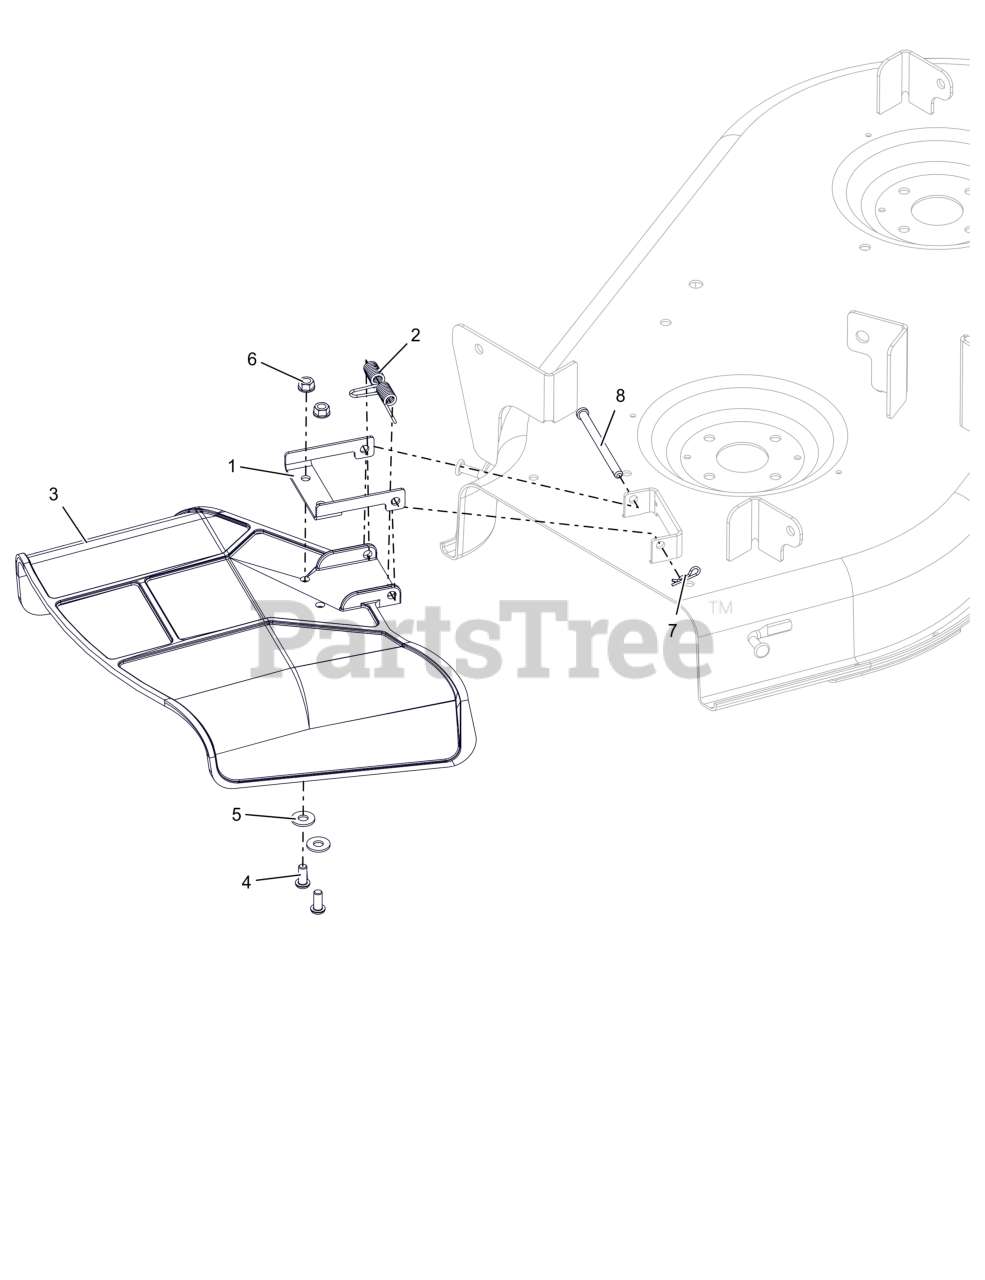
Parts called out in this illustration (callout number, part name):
1	CHUTE REINFORCEMENT
2	SPRING, TORSION
3	CHUTE, SIDE DISCHARGE
4	SCR-SKH .31-18X.75 BTNHD YWZC
5	WSHR,FLT .375X.875X.083 ZCC
6	NUT,LK-CTR-FLG .31-18 GF ZCC
7	PIN, HAIR #213 .08X1.19 ZCC
8	PIN, 5/16 X 3.88"
